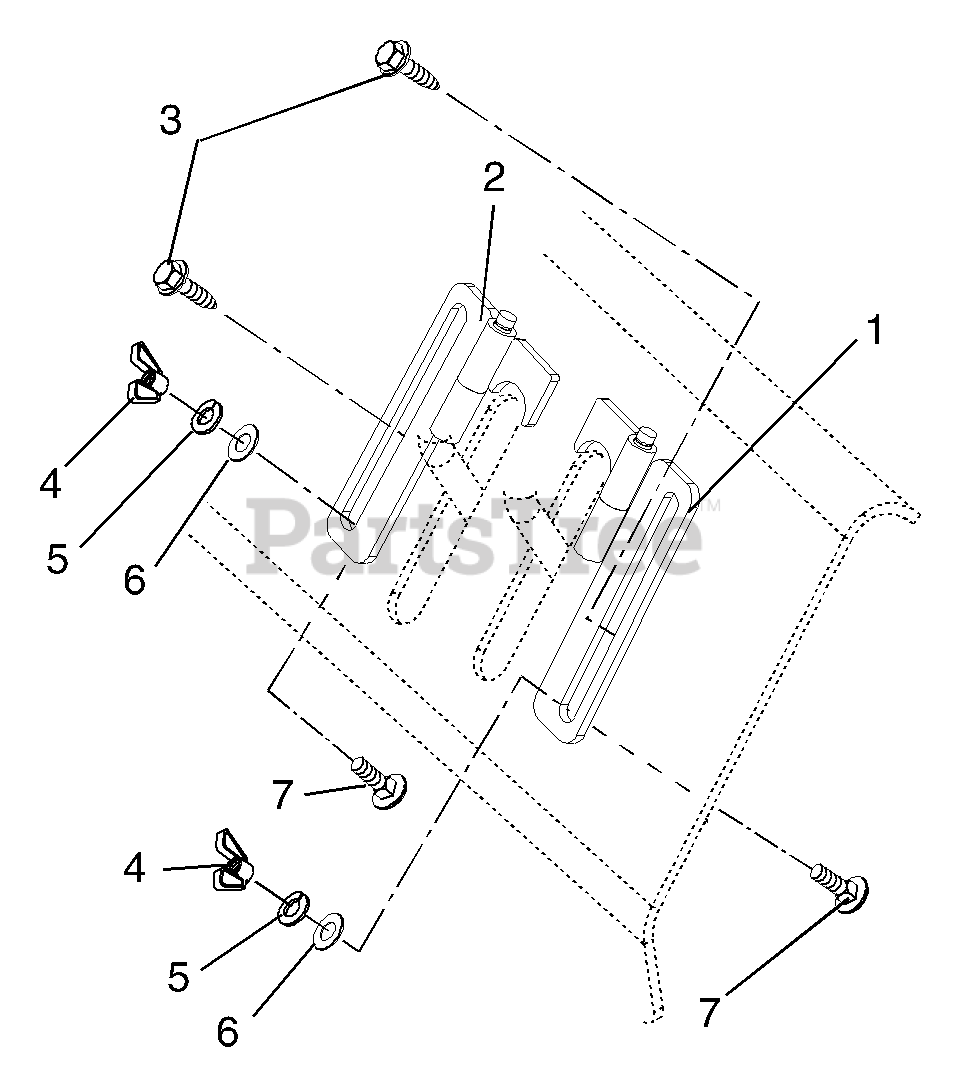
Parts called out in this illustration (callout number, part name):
1	Right Speed Control Assembly
2	Left Speed Control Assembly
3	Hex Washer Head Tapping Screw .25-20 x .50
4	Wing Nut .250-20
5	Lock Washer .25 x .062
6	Flat Steel Washer .281 x .62 x .065
7	Round Head Square Neck Bolt .25-20 x .75 Grade 5
